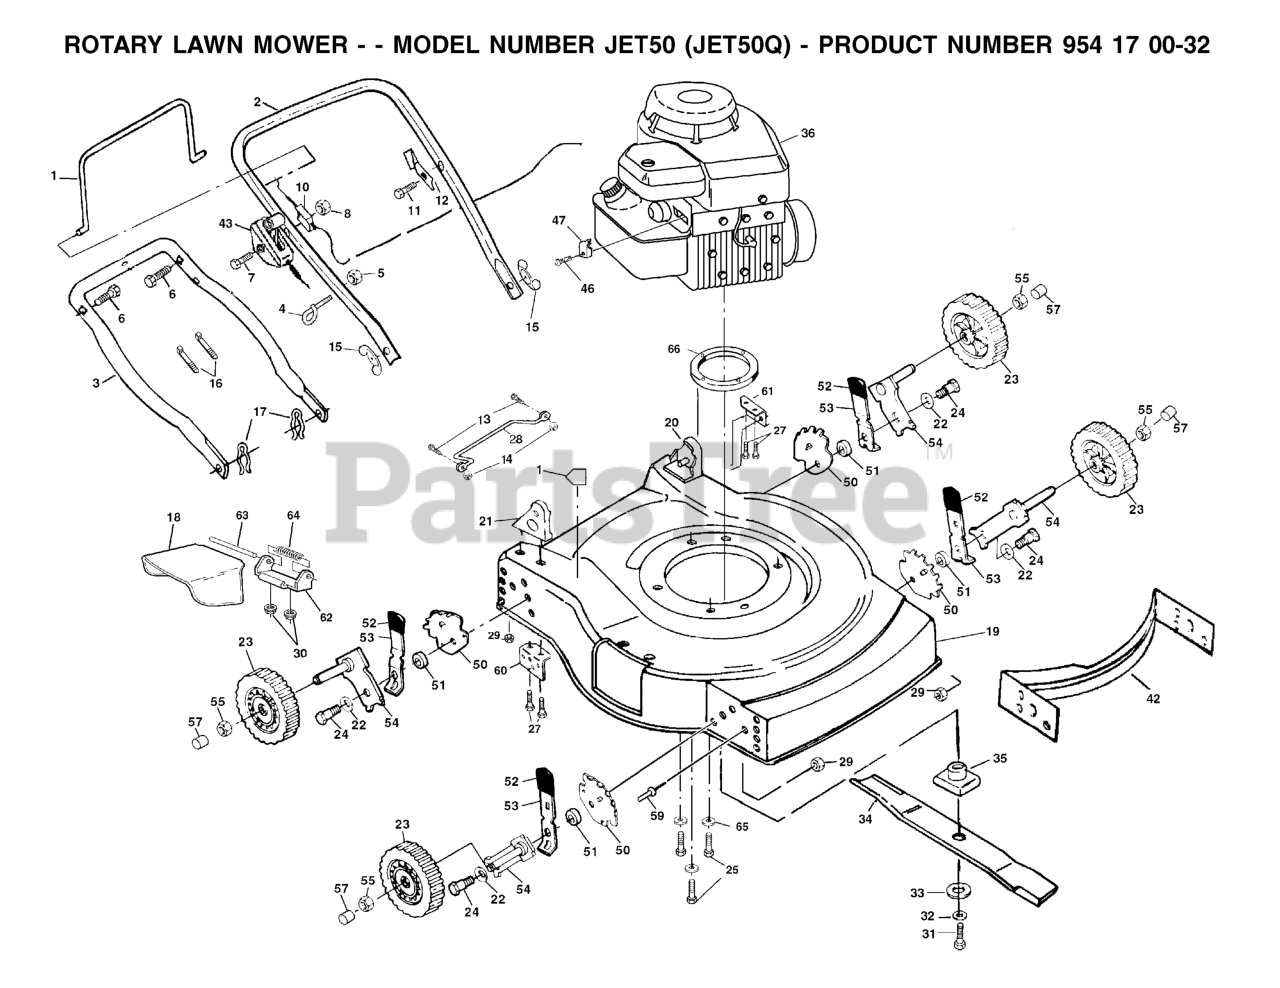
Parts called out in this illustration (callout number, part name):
1	CONTROL BAR
2	UPPER HANDLE
3	HANDLE
4	ROPE, GUIDE
5	NUT
6	HANDLE BOLT
7	SCREW 1/4-20 X 2.12
8	NUT
10	CABLE.MZR.51.RT.SP./PU.
11	TAPPING SCREW
12	BRACKET UPSTOP
13	REPL BY 817 02 10-08
15	NUT WING PM
16	TIE GUIDE
17	HAIRPIN COTTER
20	HANDLE BRACKET ASM. LH
21	HANDLE BRACKET ASM. RH
22	WASHER.BELLEVILLE (3 2 LB)
23	WHEEL
24	BOLT
27	SCREW.5/16-18X3/4
29	LOCKNUT PM
30	NUT
31	SCREW, HEX HD 3/8-24 X 1-3/8
32	LOCKWASHER
33	WASHER,HARDEN
34	20" Blade
35	BLADE ADAPTOR
41	DECAL.INTERNATIONL.CUTFINGER
46	SCREW.HEX.HEAD.WASHER.10-16
47	CABLE CLAMP(ENGINE)
50	WHEEL ADJUST BRACKET
51	RP SPACER HT ADJ
53	SELECTOR SPRING
54	AXLE, REAR
55	HEX FLANGE LOCKNT
59	RIVET BLIND
60	Bracket Support (Right)
61	BRKT SUPPORT(L)
62	BRACKET PM
63	ROD.HINGE.COMBI-C
